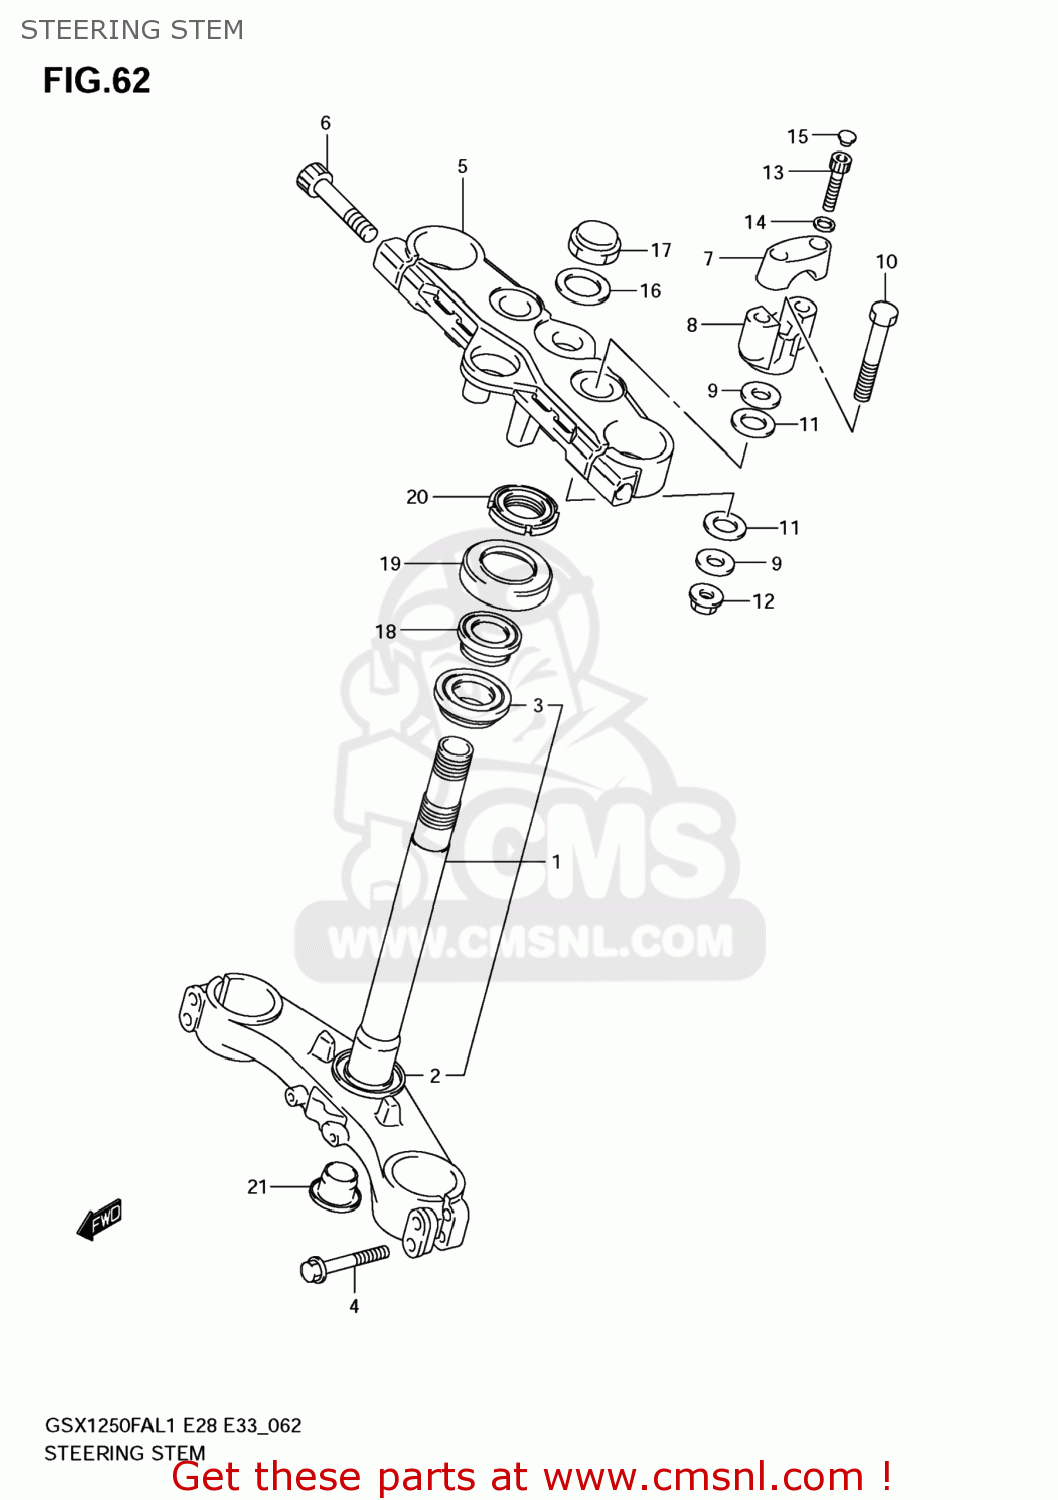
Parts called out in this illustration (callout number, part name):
1	STEM,STEERING
2	SEAL,STEERING LWR
3	BEARING(30X55X17)
4	BOLT,HOLDER AXLE(8X40)
5	HEAD,STEERING STEM
6	BOLT,OUTER
7	HOLDER,HANDLE
8	HOLDER,HANDLE UNDER
9	WASHER
10	BOLT
11	RUBBER SEAT
12	NUT
13	BOLT,HANDLE HOLDER
14	WASHER
15	CAP(OD:11)
16	WASHER
17	NUT,CAP
18	BEARING(25X47X15)
19	DUST SEAL,STEERING UPR
20	NUT,STEERING STEM
21	CAP
